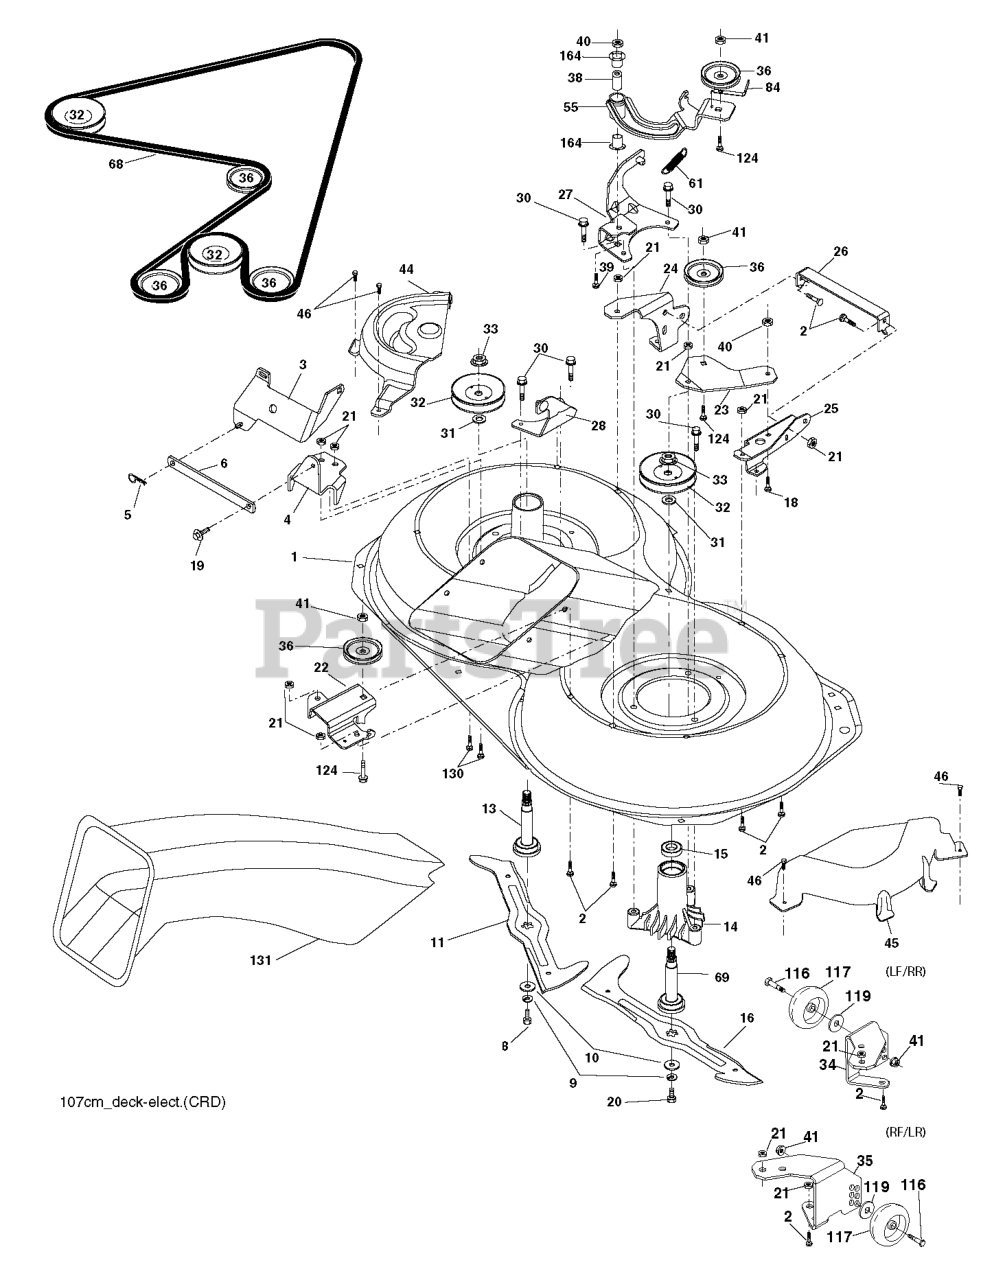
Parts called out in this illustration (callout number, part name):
1	Housing Asm. Mower 107 CRD
2	RP BOLT 5/16-18 X3/4 ZN/YEL GR
5	RETAINER-SPRNG RB
6	BAR.SWAY.92.CRD
8	BOLT.3/8-24X1.25 GR8
9	LOCKWASHER
10	WASHER.BLADE
11	BLADE.3N1.LH.CRD
13	SHAFT ASM VENT
14	HOUSING.MANDREL.VENTED (MACHD)
16	BLADE.3N1.RH.CRD
18	BOLT
19	BOLT SHD 5/16-18
20	BOLT.3/8-24X1.25GR8. LHTHRD
21	LOCKNUT
22	BRACKET.IDLER.RR.107.CRD
24	BRACKET
25	BRACKET RF
26	SUPPORT
28	BRACKET
30	SCREW, WASHER HEAD
31	WASHER.SPACER.MANDREL
32	PULLEY.MANDREL.4.80 PD.2006
33	NUT.FLANGE.LOCK.TOP
34	BRACKET
35	BRACKET
36	PULLEY.IDLER.4.25
41	NUT LOCK FLG 3/8-16 UNC
45	COVER.MANDREL.RH.CRD
46	SCREW.1/4-20X5/8
55	ARM.IDLER.107.CRD
61	SPRING
68	HEX-BELT 107 MOWER
69	SHAFT.ASM.W/LWR.BRG.RH.THREAD
84	KEEPER, BELT IDLER
116	BOLT.SHOULDER.3/8-16X3-5/8.
117	RP WHEEL. GUAGE RALLY
119	WASHER
124	BOLT.3/8-16X1.50
130	BOLT.CARR.SQNK.5/16-18UNC.X3/4
131	CHUTE BAGGER
164	BRNG T
